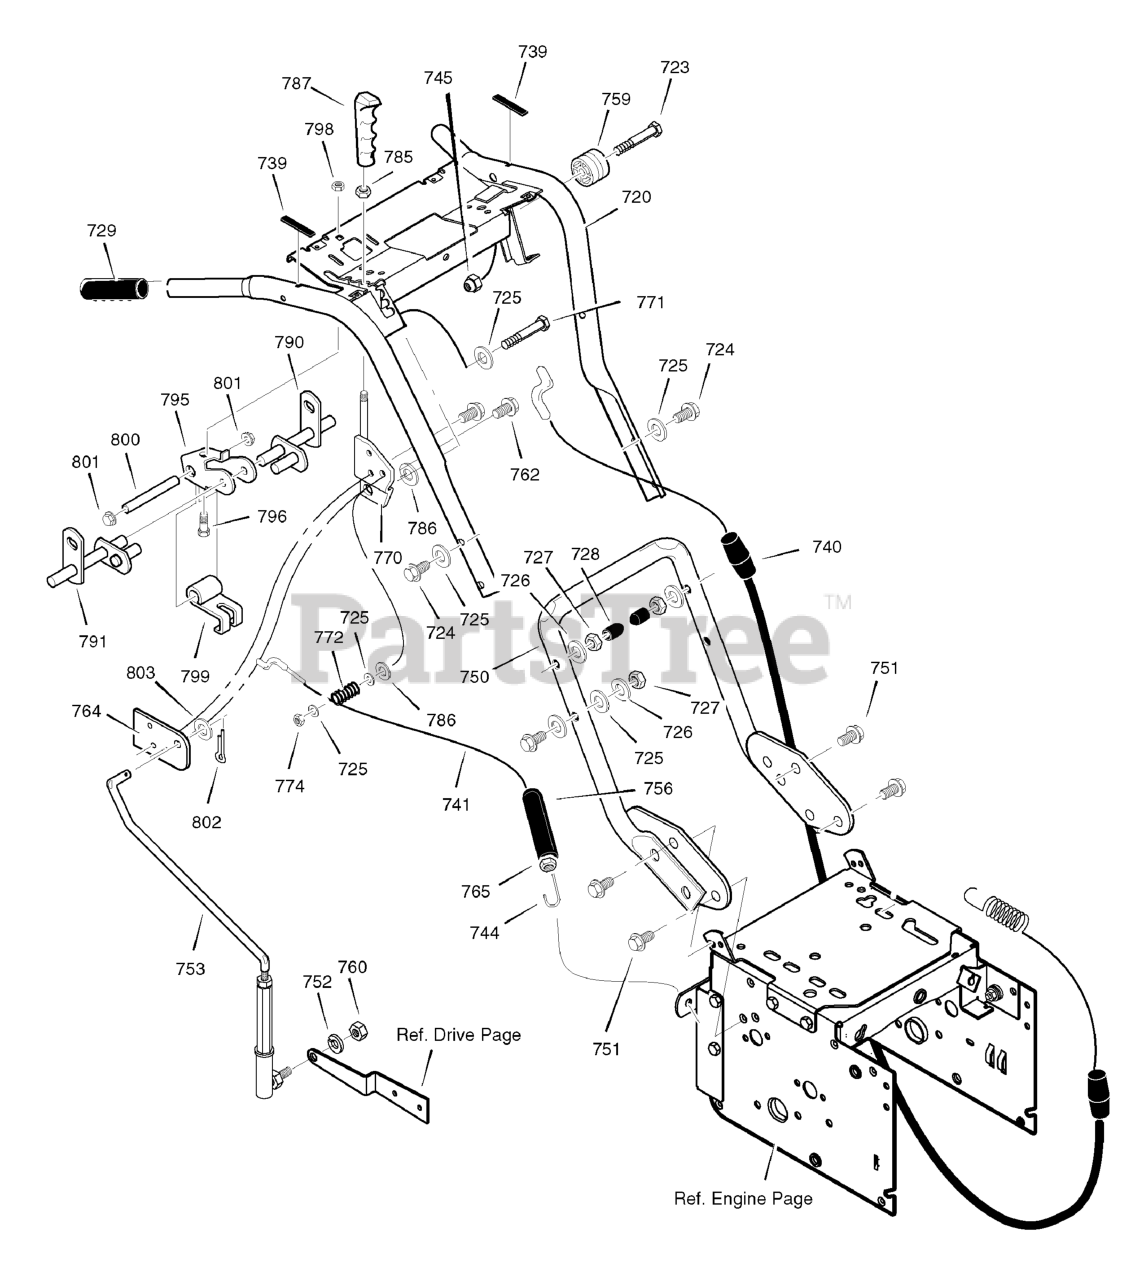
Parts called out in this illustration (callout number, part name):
720	HANDLE ASSEMBLY
723	SCREW, 3/8-16 X 2.00
724	SCREW
725	WASHER, Flat, 13/32
726	WASHER
727	NUT
728	STOP, PLASTIC
729	GRIP, HANDLE
739	BUMPER
740	CABLE, AUGER CLUTCH
741	CABLE, DRIVE
743	BRACKET, CABLE ADJUST
744	SPRING, CLUTCH
745	NUT, HEX
750	HANDLE, LOWER
751	SCREW
758	NUT 5/16-18 REGHEX
759	SPOOL, CABLE
760	BRACKET, SPOOL
762	CABLE, LOWER DRIVE
763	BOLT, HEX 1/4-20 X 1.5
765	BOOT, CABLE
770	BRACKET, SHIFT
771	SCREW
773	WASHER, Flat, 13/32
774	NUT, HEX
785	NUT, HEX
787	KNOB, SHIFT
790	ROD, ASSEMBLY LH
791	ROD, ASSEMBLY RH
795	BRACKET, CAM
796	SCREW
798	NUT, NYLOCK
799	CAM LOCK
800	PIN, SPRING PIVOT
801	NUT, PUSH ON
802	PIN, COTTER
803	FLATWASHER
804	ROD, SPEED CONTROL
805	NUT, 5/16-18
806	ADAPTER, ROD
808	BALLJOINT, STEEL
809	WASHER
810	NUT, 5/16-18
811	BEARING, FLANGE
812	ROD, YOKE
813	RETAINER, RING
